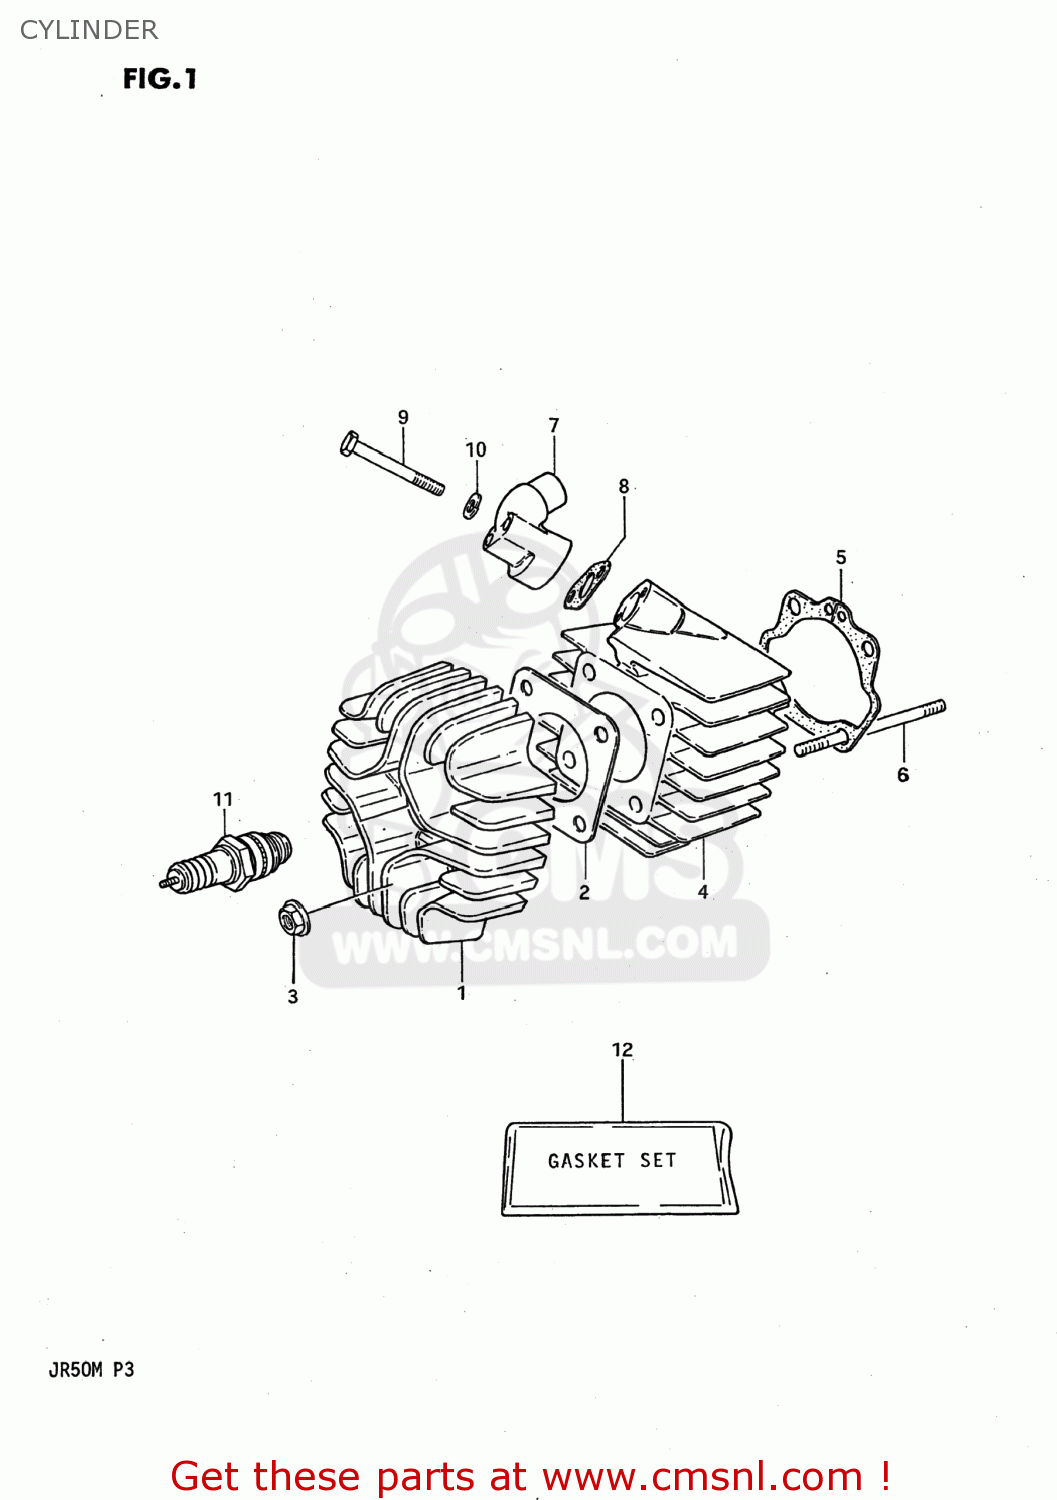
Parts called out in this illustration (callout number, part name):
1	HEAD,CYLINDER
2	GASKET,CYLINDER HEAD (NAS)
3	NUT
4	CYLINDER
5	GASKET,CYLINDER (MCA)
6	BOLT,STUD
7	PIPE,INTAKE
8	GASKET (NAS)
9	BOLT
10	WASHER,LOCK
11	PLUG,SPARK(BP4H)
12	GASKET SET (MCA)
